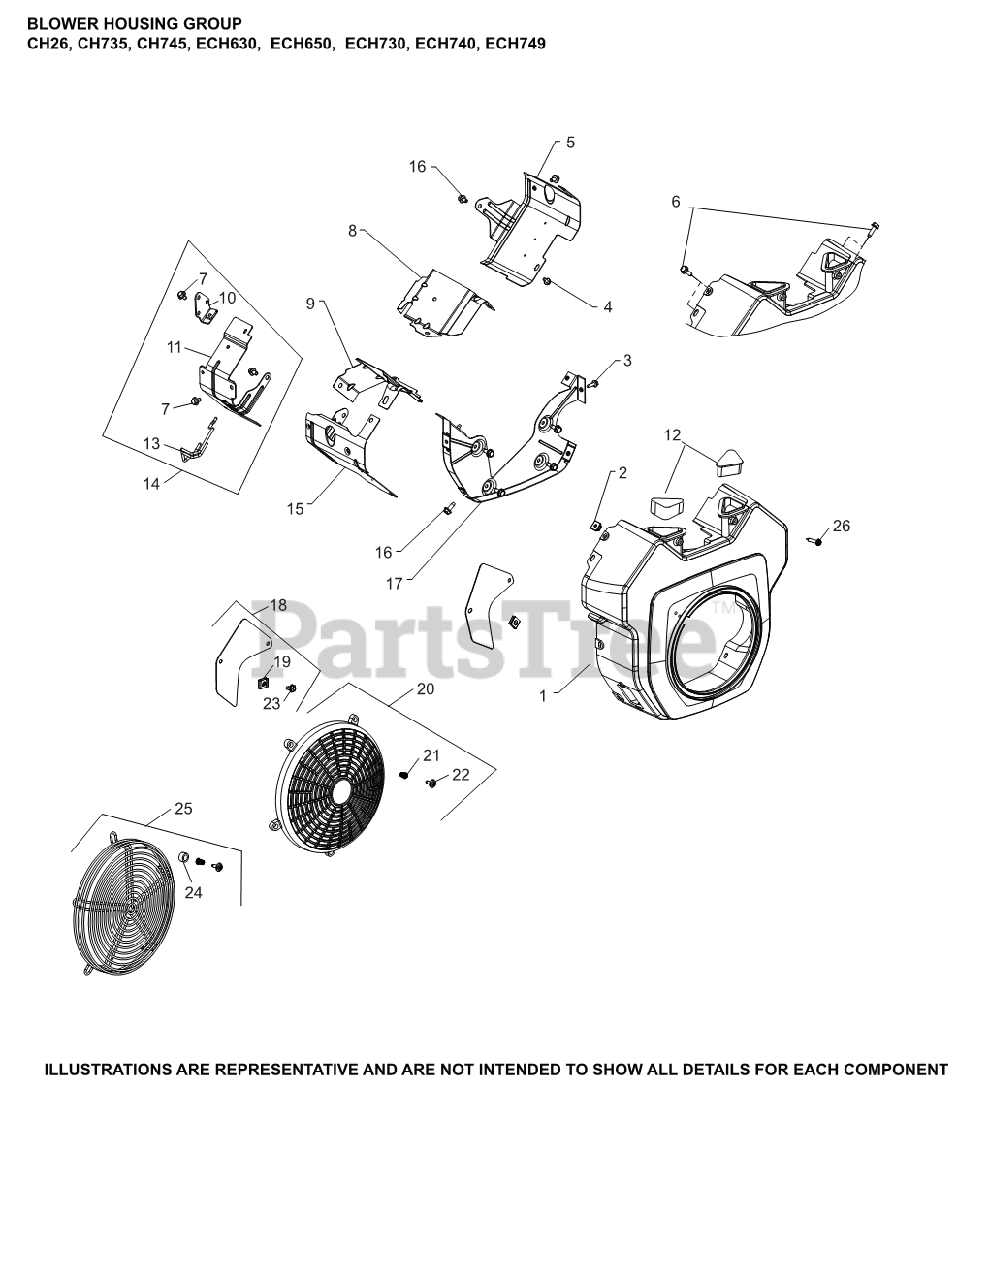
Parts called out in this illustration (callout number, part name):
1	HOUSING, BLOWER
3	SCREW, THREAD FORMING
4	SCREW, THREAD FORMING
5	BAFFLE, RIGHT BARREL
6	SCREW, THREAD FORMING
8	BAFFLE, VALLEY #1 CYLINDER
9	BAFFLE, VALLEY #2 CYLINDER
12	COVER, BLOWER HOUSING USE 24 096 160-S
15	BAFFEL, LEFT BARREL
16	SCREW, THREAD FORMING
17	PLATE, BACKING
18	KIT, ACCESS PANEL
19	CLIP, BAFFLE MOUNTING USE 25 154 37-S
23	SCREW, THREAD FORMING
